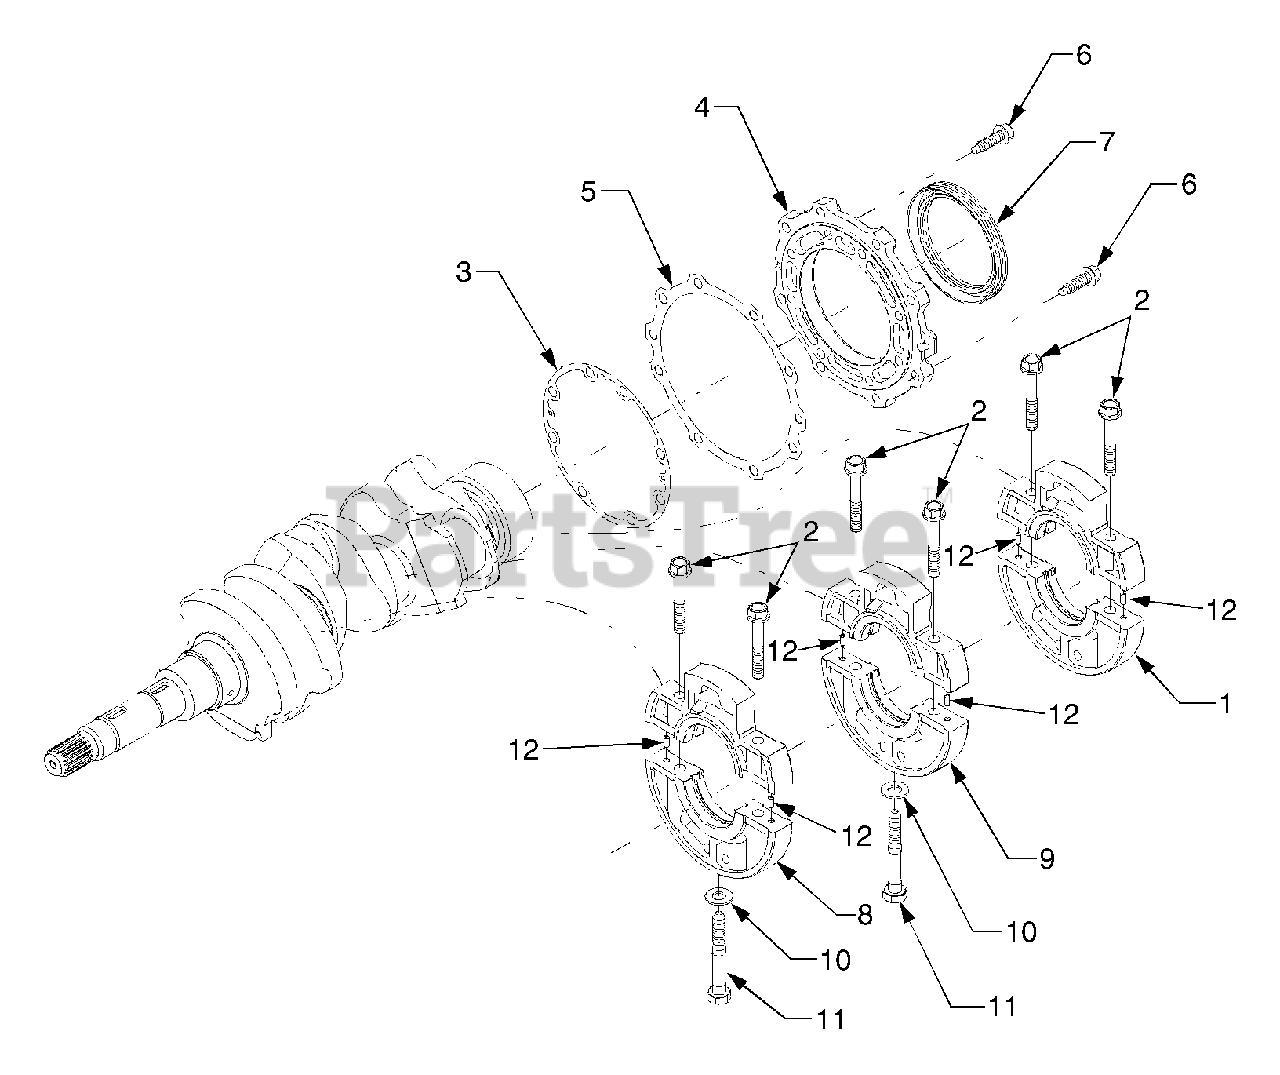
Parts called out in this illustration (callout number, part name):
1	Main Bearing Case Ass'y
2	Bolt, Bearing Case 1
3	Gasket, Bearing Case
4	Cover, Main Bearing Case
5	Gasket, Bearing Case
6	Pin, Flange Bolt
8	Main Bearing Case 1 Ass'y
9	Main Bearing Case 2 Ass'y
11	Bolt 2, Bearing Case
12	Pin, Straight
